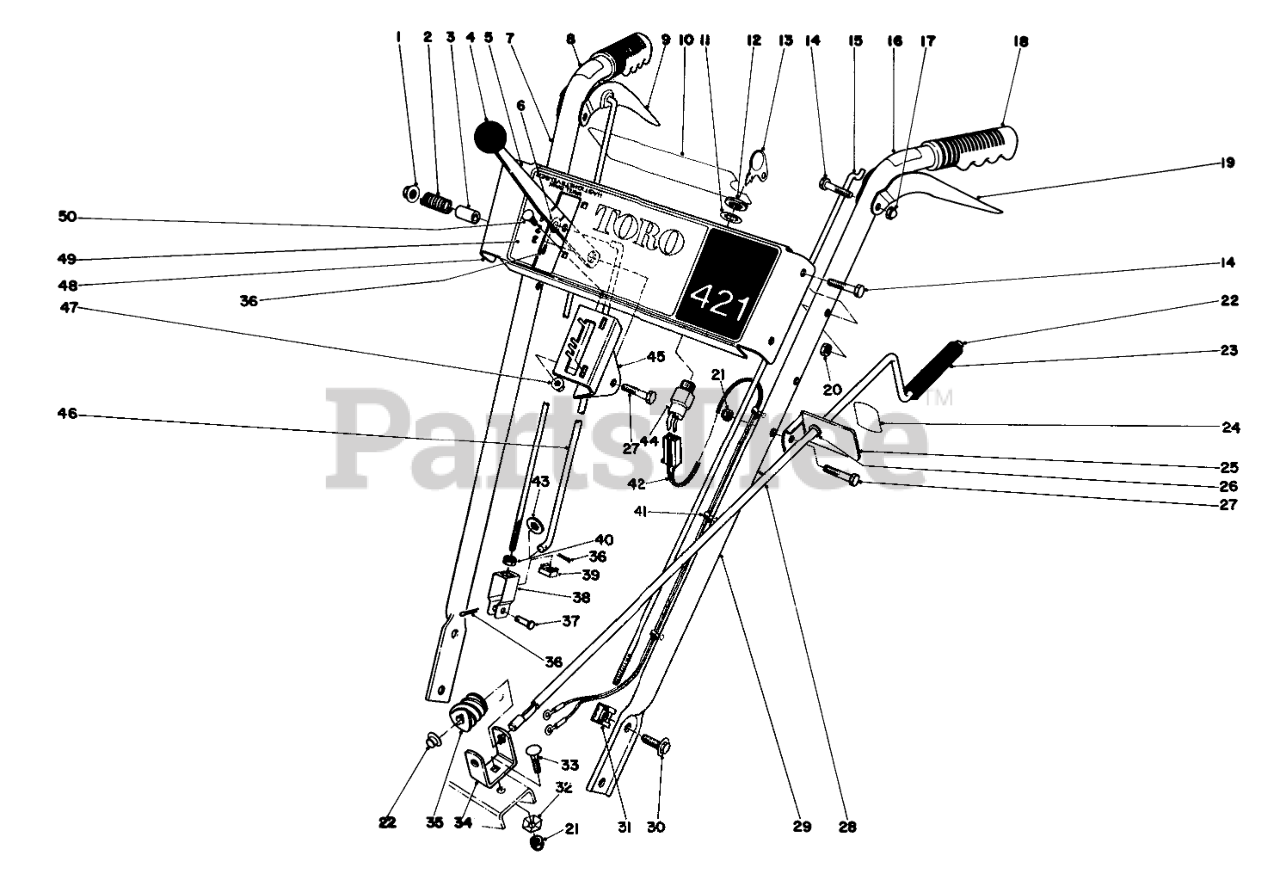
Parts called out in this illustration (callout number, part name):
1	NUT-HF
2	SPRING
3	SPACER
5	SPEED SELECTOR B
6	WASHER-FLAT
7	Handle Ring
8	Decal-Auger Drive
9	Lever-Auger Control
10	Decal-Escutcheon Back
11	WASHER-TOOTH, INTERNAL
12	NUT-HH
13	Key
14	SCREW-HH
15	Link Upper
16	Decal-Wheel Drive
17	NUT-CAP
18	Grip
19	Lever-Traction Control
21	NUT-LOCK, NI
22	RETAINER-PUSH ON
23	GRIP-CONTROL, CHUTE
24	CHUTE DECAL
25	Bracket-Chute Control Mtg. (Incl. Ref. #24 & 26)
26	Bushing
27	SCREW-HH
28	ROD-CONTROL, CHUTE
29	Handle Left
30	SCREW-HHF
32	WASHER-LOCK
33	BOLT-CARR
34	BRACKET-WORM
35	GEAR-WORM, CHUTE
36	PIN-COTTER
37	PIN-CLEVIS
38	CLEVIS
39	NUT-RETAINED
40	NUT-JAM
41	TIE-CABLE
42	WIRE HARNESS
43	WASHER-PLAIN
44	SWITCH-ON / OFF
45	Mount-Speed Selector
46	ROD-SELECTOR, SPEED
47	NUT-HHF
48	Panel-Escutcheon
49	Decal-Escutcheon
50	SCREW-CARRIAGE
